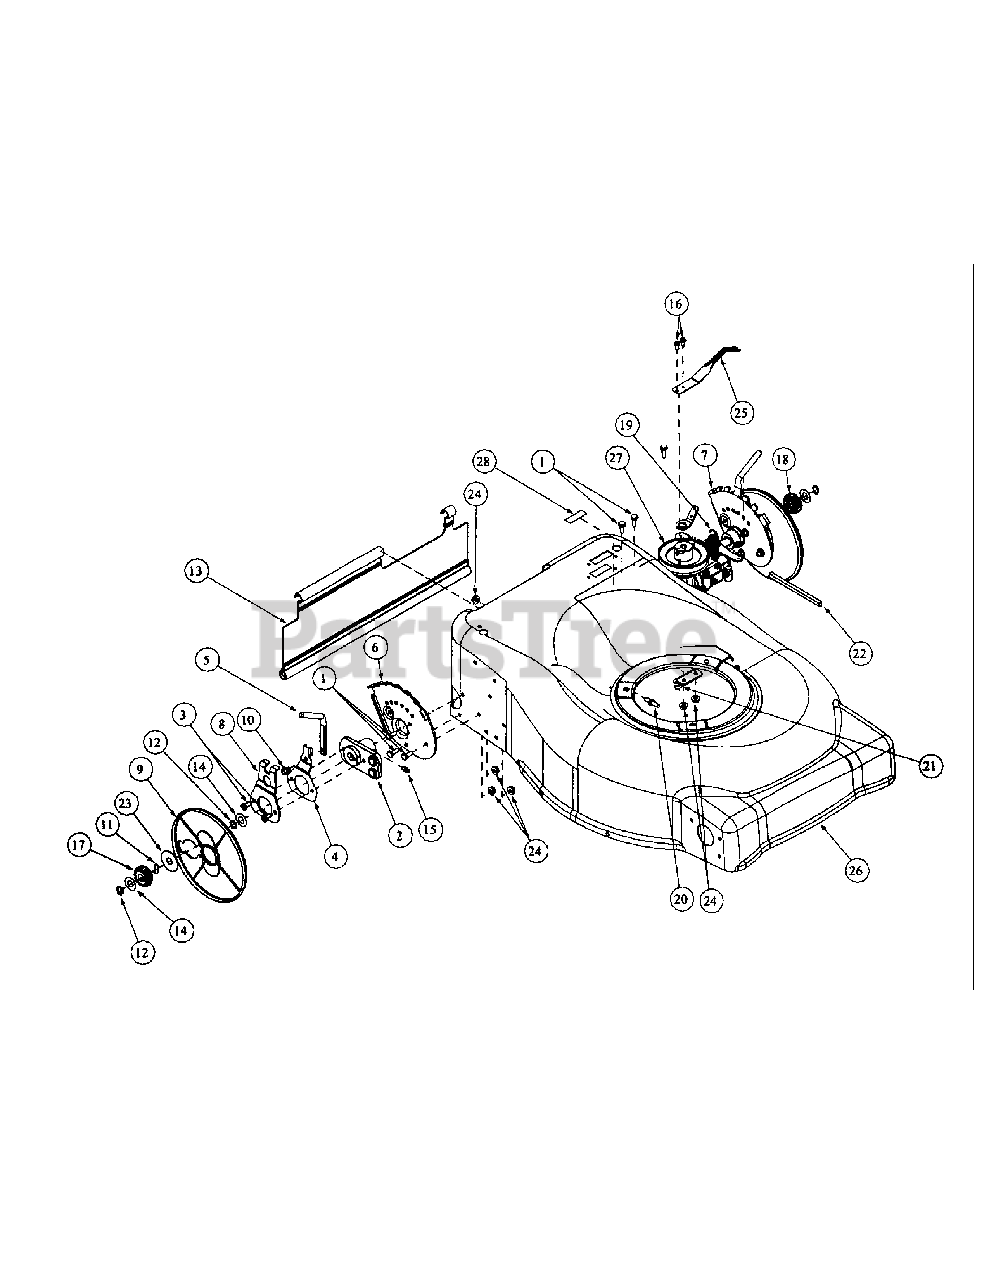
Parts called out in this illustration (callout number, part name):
1	Hex, Cap Screw, 1/4-20, .620
2	Pivot, Wheel, Bracket Assembly, 2 Pos
3	Screw, TT, 1/4-20, .625
4	Height Adjuster, Spring Plate
5	Height Adjuster, Handle
6	Height Adjuster, Bracket, Right Rear
7	Height Adjuster, Bracket, Left Rear
8	Spring Lever, Support, Bracket
9	Drive Wheel, Dust, Cover
10	Screw, 1/4-20, .375, Index Washer
11	Dowel Pin, 3/16 x 3/4
12	Retainer Ring, .500 Dia Heavy Duty
13	Trailshield, 6.12 x 17.91 Long
14	Flat Washer, .508 ID x 1.00 OD x .020
15	Grease Fitting
16	Screw, #10-24-24, 0.500, Hex Index Washer
17	Pinion Gear, 15T, With Ratchet, R
18	Pinion Gear, 15T, With Ratchet, L
19	Extension Spring, .75 OD x 2.37
20	Belt, Pin, Keeper
21	Transmission, Spring Bracket, Tuff Torque
22	Belt, V Type, 3/8 x 32.92 Long
23	Thrust Washer, .510 x 1.562 x .03
24	Nut, 1/4-20, Hex Flange, Lock
25	Shift Spring
26	21" Deck
27	Transmission Assembly, 3-Speed
28	Label, Shift, 21
